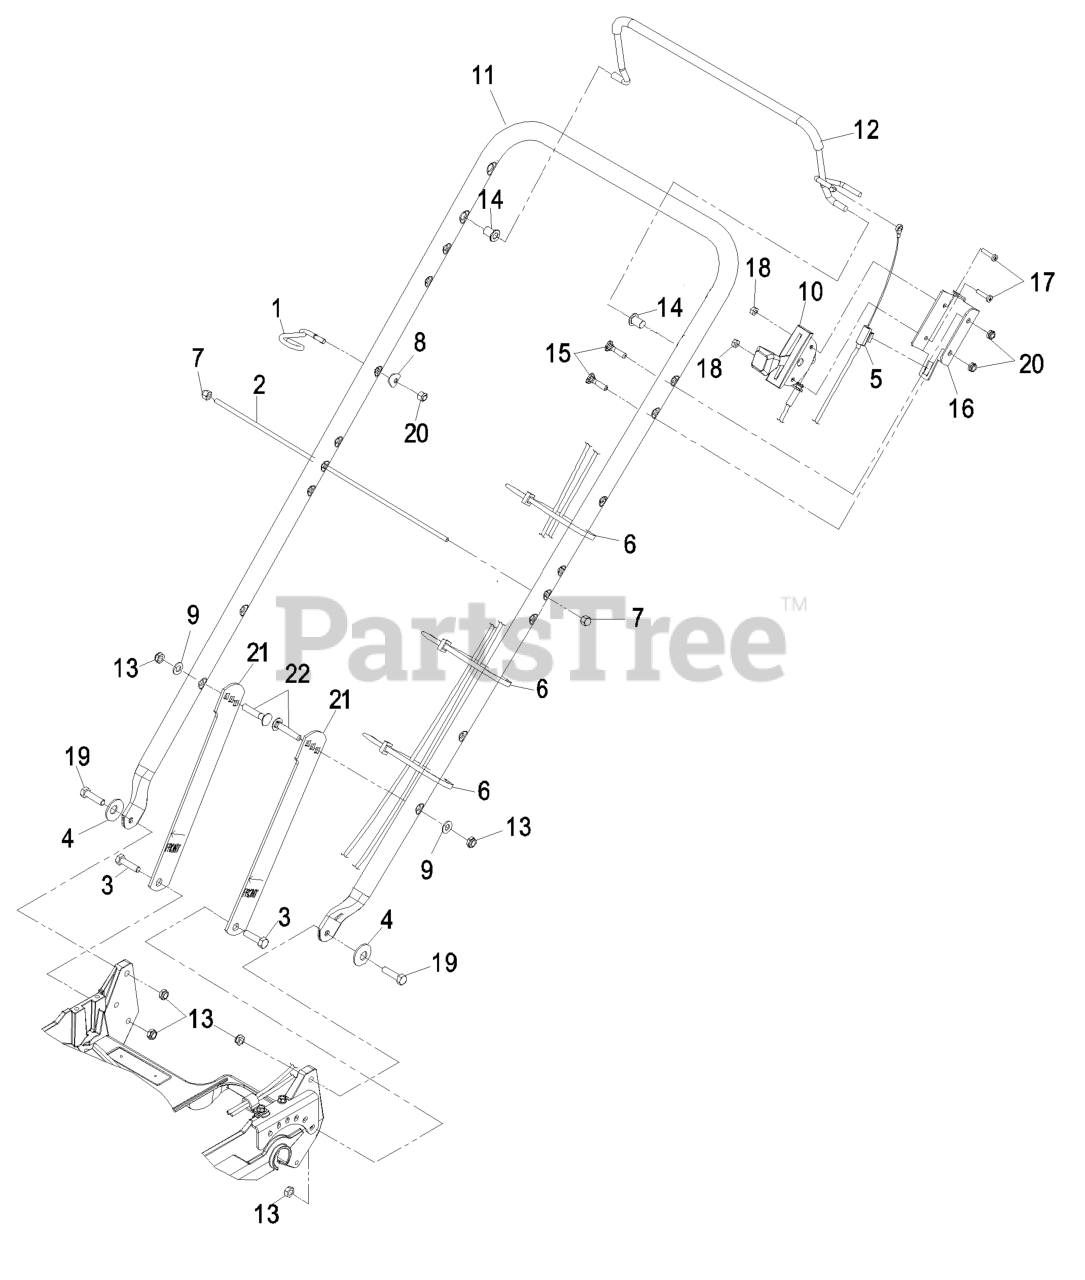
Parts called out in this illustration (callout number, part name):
1	GUIDE-ROPE
2	ROD, BAG SUPPORT
3	SCREW-HH
4	WASHER-BELLEVILLE
5	CABLE,BRAKE KAWASAKI
6	TIE-CABLE
7	NUT-CAP
8	WASHER
9	WASHER-PLAIN
10	CABLE,THROTTLE KAWASAKI
11	HANDLE M21
13	NUT-LOCK, NI
14	BUSHING
15	BOLT-HANDLE
16	BRACKET, THROTTLE
17	SCREW-PPH
18	NUT-LOCK, NI
19	SCREW-HH
20	NUT-LOCK, NI
21	Latch, Handle
22	BOLT-CARR
